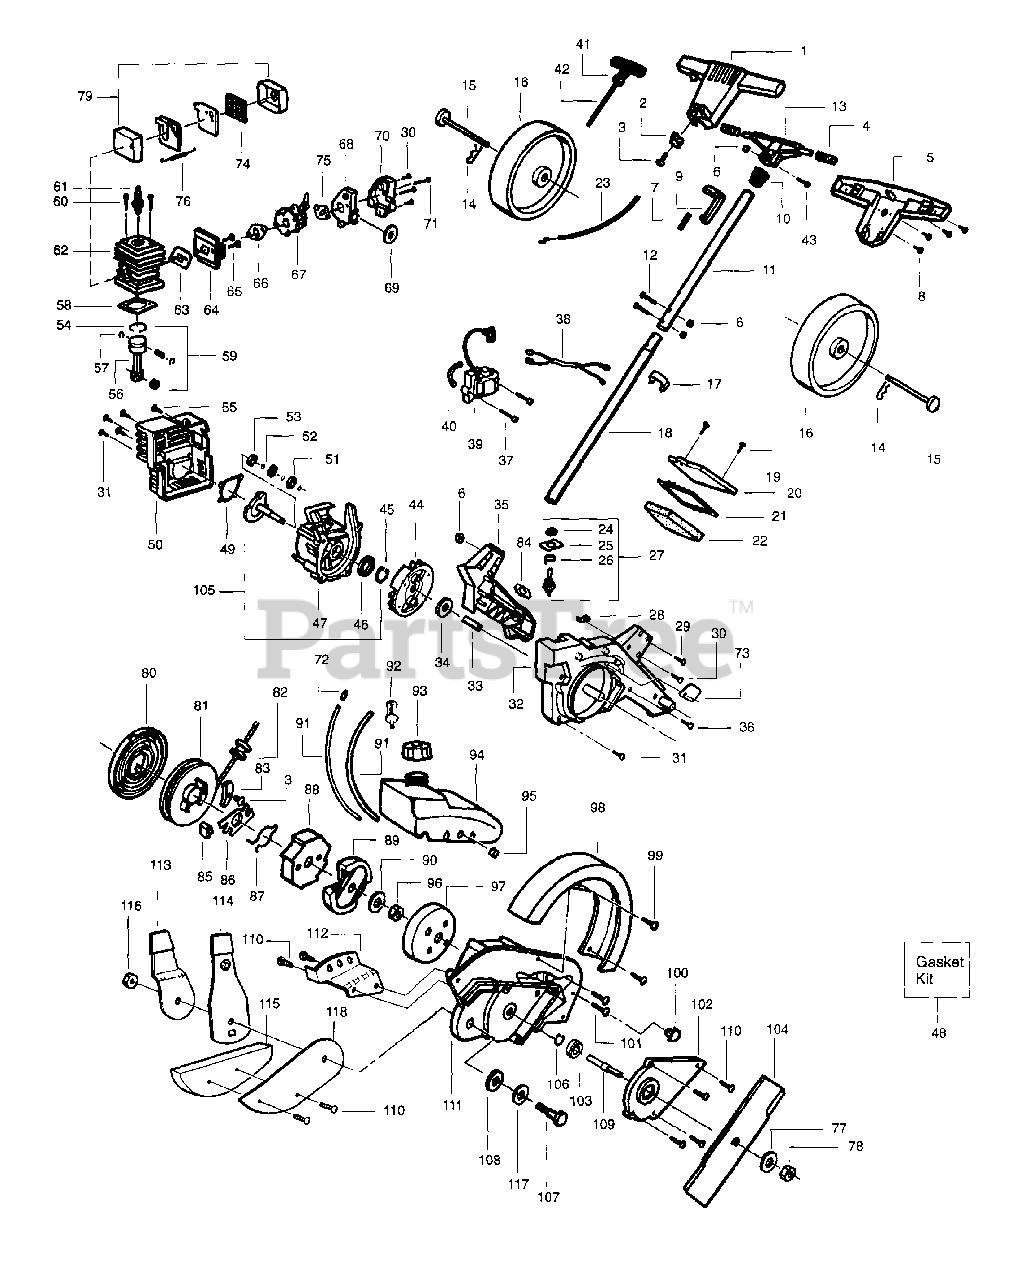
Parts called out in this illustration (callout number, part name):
1	Upper Handle
2	Handle Eyelet
4	Spring Isolator
5	Lower Handle
7	Throttle Spring
9	Throttle Trigger
10	Handle Spring
11	Upper Handle Tube
12	Bolt - Shoulder Tube
13	Coupling - Handle
14	Pin Bridge
15	Axle Pin
16	Rear Wheel
17	Clamp - Cable
18	Lower Handle Tube
20	Air Filter Cover
21	Gasket - Cover
22	Air Filter Foam
23	Throttle Cable
24	Boot w/Nut
25	Switch Indicating Plate
26	Grounding Terminal
27	Switch Grounding Assy
28	Speed Nut
31	Screw
32	Fan Housing
33	Flywheel Spacer
34	Washer - Flat
35	Axle Cover
38	Switch Wire Ass'y.
39	Ignition Module
40	Spacer - Ignition Module
41	Starter Handle
42	Rope Kit
44	Flywheel Ass'y.
45	Retaining Ring - C'case
46	Seal Crankcase
47	Crankcase Ass'y.
48	Gasket Kit
49	Gasket - Crankcase/Shroud
51	Outer Bearing
52	Retaining Ring - C'shaft
53	Inner Bearing
54	Piston Ring
56	Connecting Rod Ass'y.
57	Piston Pin Retainer
58	Gasket - Cylinder
59	Piston Kit
61	Spark Plug (RCJ - 8Y)
62	Cylinder Kit
63	Gasket - Cylinder/Garb Adaptor
64	Carb. Adaptor
66	Carb. Gasket
67	Carburetor w/Choke (WT308)
68	Air Box Base
69	Foam Seal
70	Airbox Cover
72	Fuel Line Fitting
73	Fuel Line Retainer
74	Muffler Screen
75	Gasket - Bracket to Carb.
76	Muffler Spring
77	Washer - Belleville
79	Muffler Kit
80	Starter Spring
81	Starter Pulley Kit
83	Rope Retainer
84	Gasket - Tube
85	Starter Dog
86	Starter Cam
87	Starter Dog Wire
88	Starter Cup
89	Clutch Ass'y.
90	Washer - Flywheel
91	Fuel Line Kit
92	Fuel Pick - up Ass'y.
93	Fuel Cap Ass'y.
94	Fuel Tank Ass'y.
95	Isolator - Crankcase (Fuel Tank)
97	Drum Clutch
98	Front Shield
100	Dustplug
102	Bearing Holder Ass'y.
103	Washer - Thrust
105	C'case & C'shaft Ass'y.
106	Retainer Ring (Flat)
107	Shoulder Bolt
108	Washer - Bolt Adjust
109	Shaft - Output
111	Gear Box Ass'y.
112	Back Plate
113	Lever Limiter
114	Lever Adjustment Ass'y.
116	Nut - Swing Arm
117	Wave Washer
118	Swing Arm
